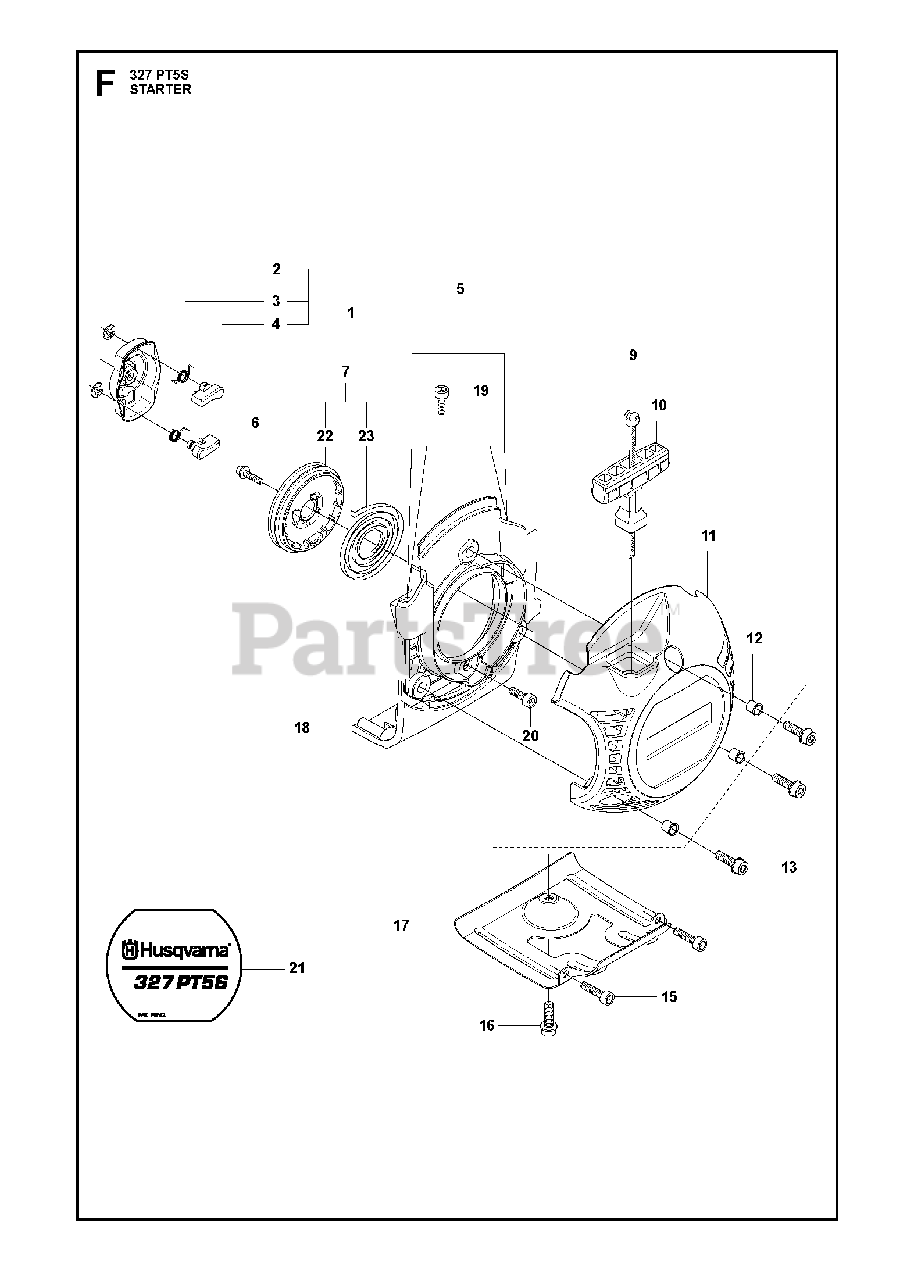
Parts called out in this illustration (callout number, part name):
1	STARTER PAWL BRIDGE
2	E-RING 4
3	SPRING
4	STARTER PAWL
5	STARTER ASSY
6	SCREW
7	STARTER PULLEY
8	SPACING SLEEVE
9	STARTER ROPE
10	STARTER HANDLE
11	STARTER HOUSING
12	SPACING SLEEVE
13	SCREW
16	SCREW
18	BRACKET ASSY
19	SCREW IHSCFMO
20	SCREW
23	STARTER SPRING
